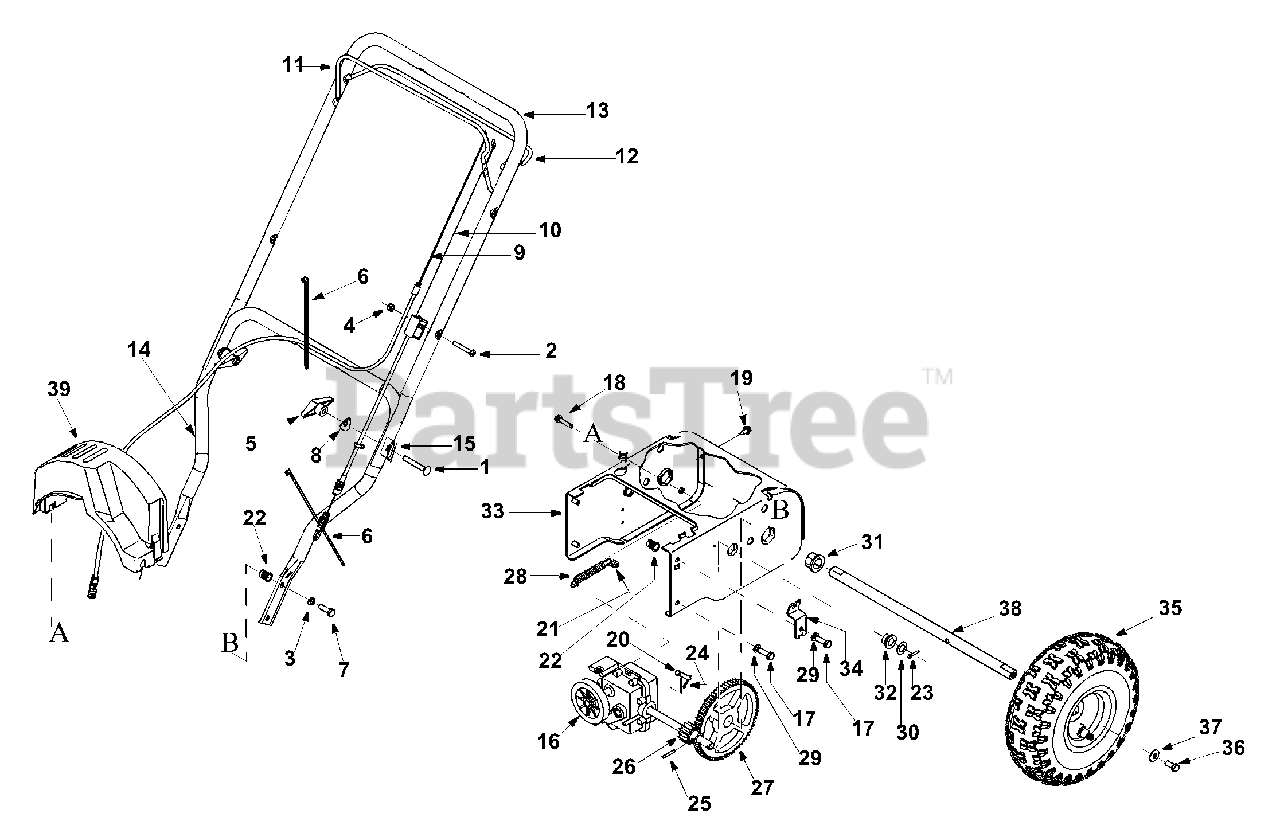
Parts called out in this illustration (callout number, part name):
1	Carriage Screw 5/16-18 x 2.
2	Mach. Screw 1/4-20 x 1.825"
3	Hex Bolt 5/16-18 x 1.0"
4	Hex Lock Nut 1/4-20
5	Handle Knob Assembly
6	Cable Tie
7	Lock Washer
8	Saddle Washer
9	Auger Cable
10	Drive Cable
12	Drive Bail
15	Handle Tab
16	Transmission Assembly
17	Hex Bolt 5/16-18 x 1.0"
18	TT Screw 1/4-20 x 1.25"
19	TT Screw 1/4-20 x .625"
20	Clevis Pin
21	Hex Lock Nut 1/4-20
22	Nut Insert
23	Cotter Pin
24	Cotter Pin
25	Roll Pin
26	Pinion 14T
27	Gear 70T
28	Extension Spring
29	Lock Washer
30	Flat Washer
31	Hex Flange Bearing
32	Hex Flange Bearing
36	Lock Bolt 5/16-24 x 0.75"
37	Bell Washer
38	Axle
39	Belt Cover
